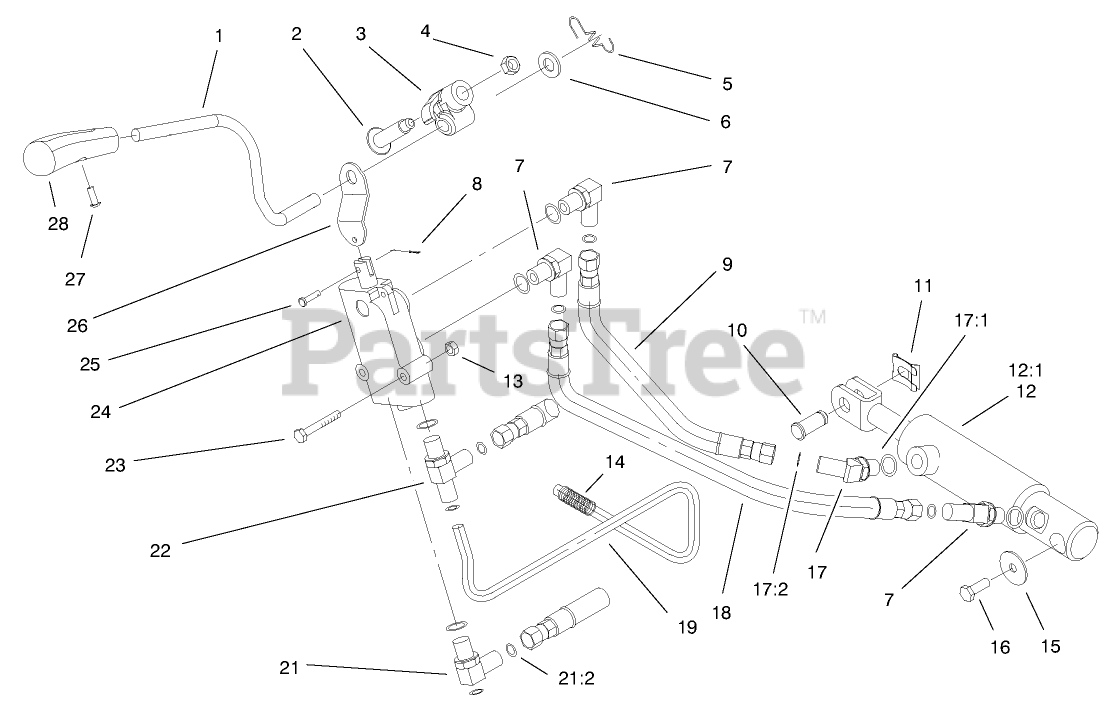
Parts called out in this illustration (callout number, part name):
1	HANDLE-LIFT
2	BOLT-SHOULDER
3	TRUNNION-LEVER, LIFT
4	NUT-JAM, LOCKING
5	SPRING-EXTENSION, LIFT
6	WASHER
8	PIN-COTTER
9	HOSE ASM
10	PIN-CLEVIS
11	CLIP-PIN
12	LIFT CYLINDER ASM
12:1	KIT-SEAL
13	NUT-LOCK, NI
14	COVER-BRACE
15	WASHER-FLAT
16	SCREW-THREAD LOCKING
17:1	O-RING
17:2	O-RING
18	HOSE ASM
19	TUBE-HYD
22	FITTING-TEE
23	SCREW-HH
24	VALVE-HYD
25	PIN-CLEVIS
26	LINK-LIFT
27	SCREW-PPHTF
28	KNOB - LIFT
28	KNOB-LIFT
